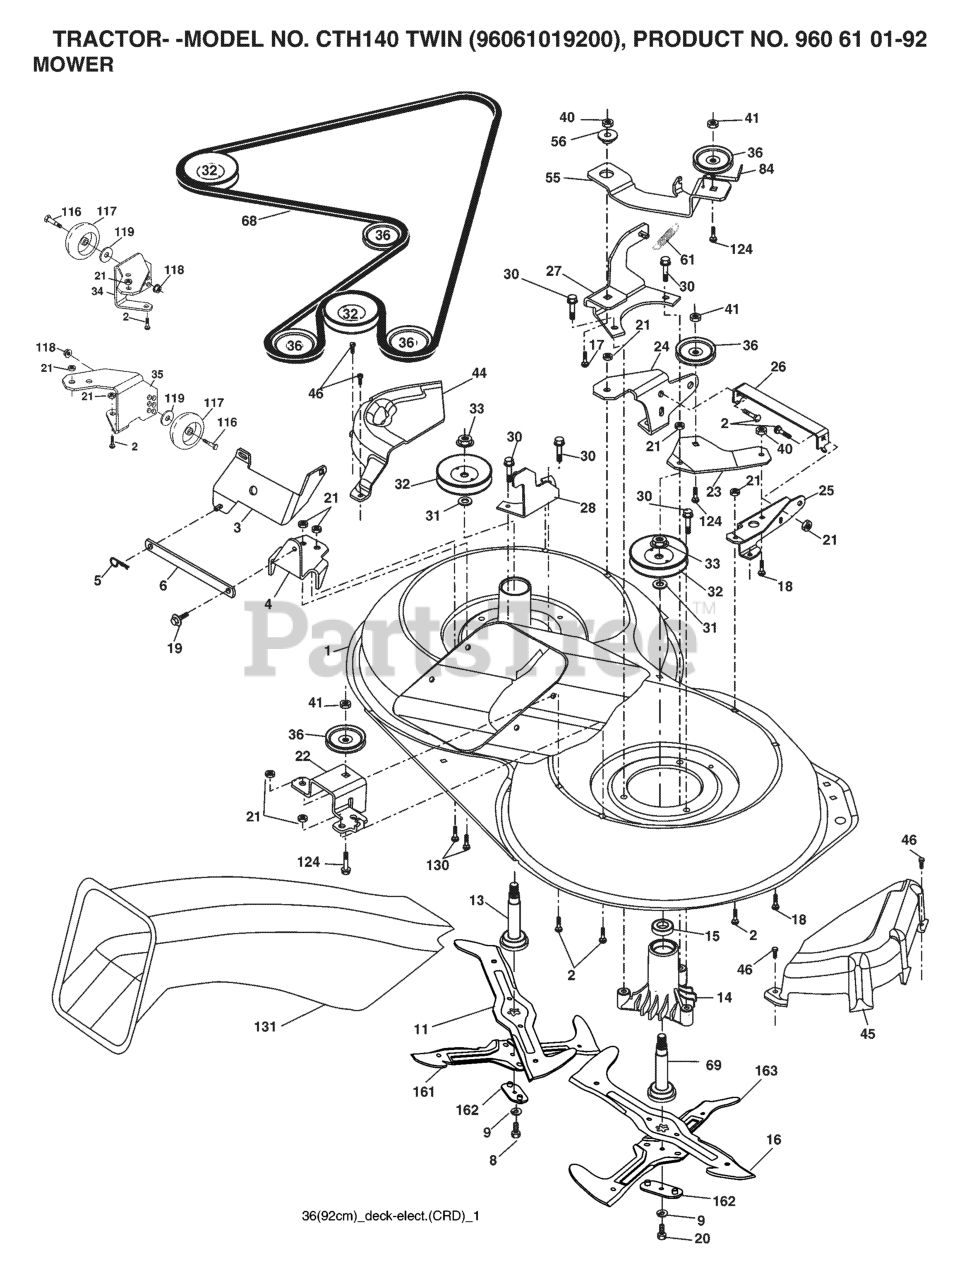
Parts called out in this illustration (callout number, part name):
2	RP BOLT 5/16-18 X3/4 ZN/YEL GR
5	RETAINER-SPRNG RB
6	BAR.SWAY.92.CRD
8	BOLT.3/8-24X1.25 GR8
9	LOCKWASHER
13	SHAFT ASM VENT
14	HOUSING.MANDREL.VENTED (MACHD)
17	BOLT.3/8-14X1.25
19	BOLT SHD 5/16-18
20	BOLT.3/8-24X1.25GR8. LHTHRD
21	LOCKNUT
26	SUPPORT
30	SCREW, WASHER HEAD
31	WASHER.SPACER.MANDREL
33	NUT.FLANGE.LOCK.TOP
36	PULLEY.IDLER.4.25
41	NUT LOCK FLG 3/8-16 UNC
45	COVER.MANDREL.RH.CRD
46	SCREW.1/4-20X5/8
55	ARM.IDLER.92 CRD.2006
56	SPACER.RETAINER.MOWER
61	SPRING
68	BELT.DRIVE.92CM.CRD.2006
69	SHAFT.ASM.W/LWR.BRG.RH.THREAD
84	KEEPER, BELT IDLER
116	BOLT.SHOULDER.3/8-16X3-5/8.
117	RP WHEEL. GUAGE RALLY
118	LOCKNUT
119	WASHER
124	BOLT.3/8-16X1.50
130	BOLT.CARR.SQNK.5/16-18UNC.X3/4
131	CHUTE BAGGER
